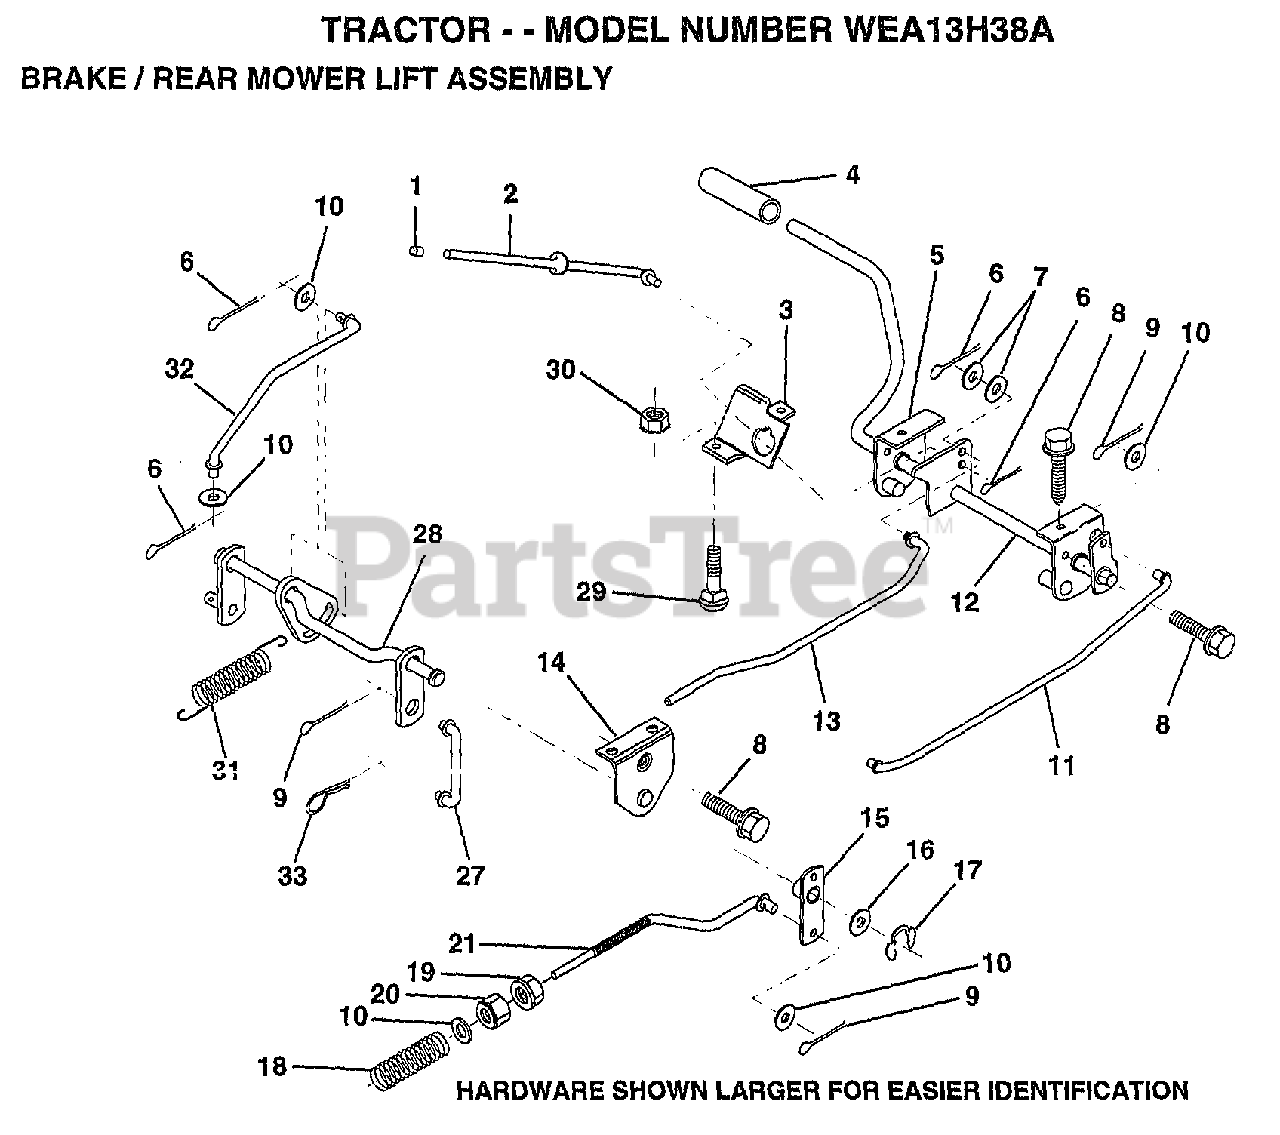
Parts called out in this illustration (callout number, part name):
1	PLUNGER CAP T
2	"ROD,PARK BRAKE"
3	"BRKT,PARK BRAKE"
4	FOOT PEDAL COVER
5	BRK ASM CLUT LH
7	WASHER
9	COTTER PIN
10	WASHER
11	"ROD,FRT BRAKE"
12	PEDAL ASM CL/BK36
13	"ROD,CLUTCH"
14	"BRKT,LIFT SHAFT"
15	PVT BRAKE ARM ASM
16	WASHER T
17	KLIP RING
18	SPRING ROD BRAKE
19	NUT
20	NUT
21	ROD.BRAKE.HYDRO
27	LINK LIFT REAR LR
28	LIFT.ASM.REAR.LR
31	COUNTER SPRING
32	LINK LIFT LEVER
